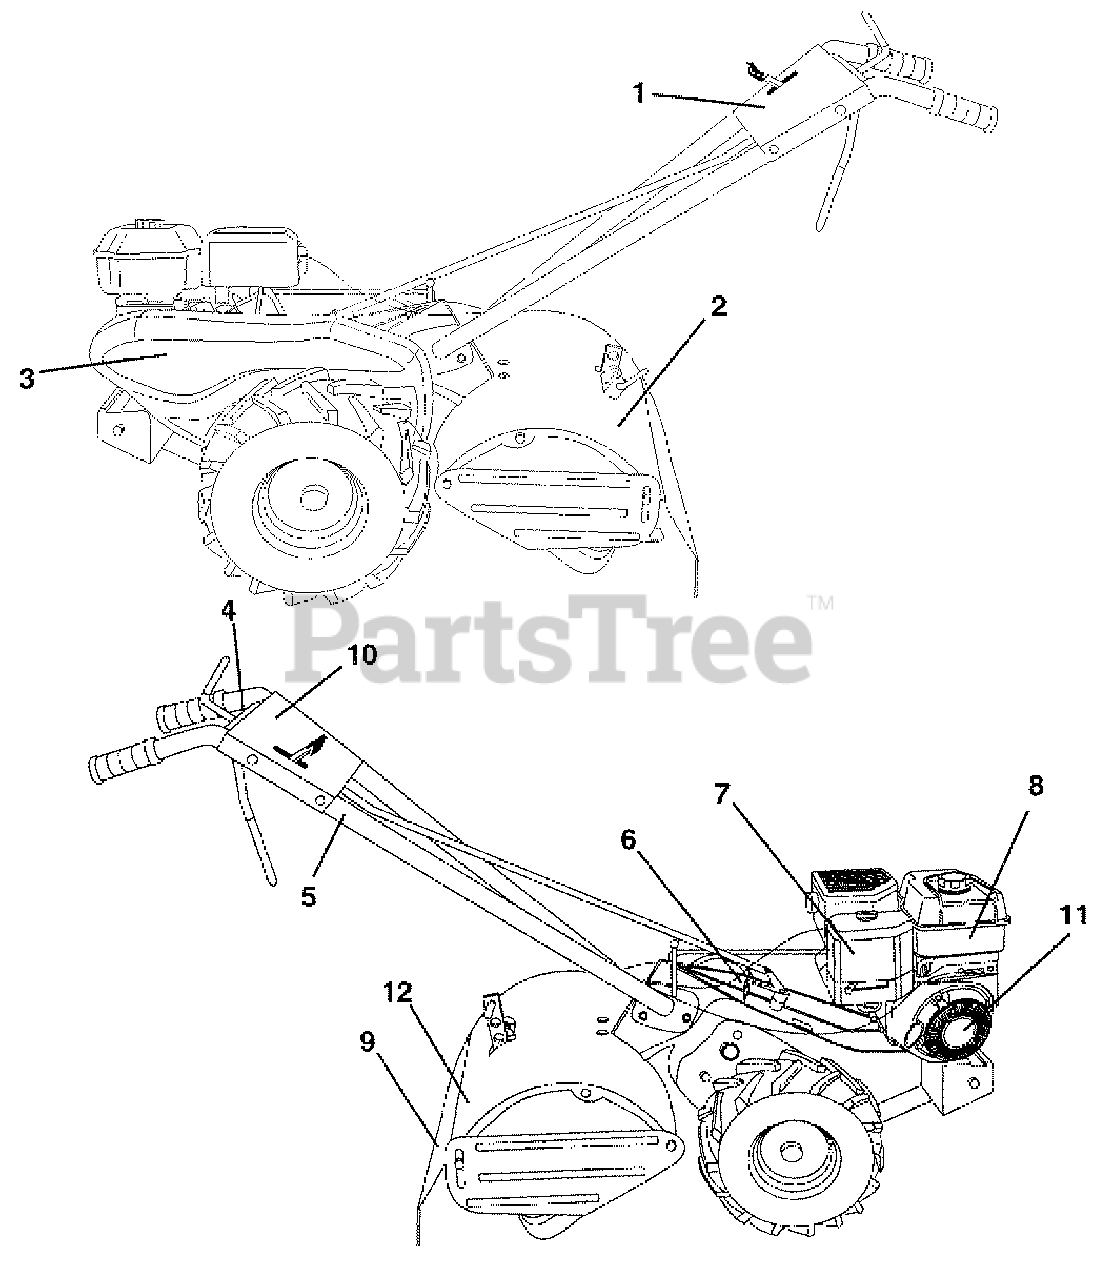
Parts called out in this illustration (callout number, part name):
1	Decal, Logo
2	Decal, Description
3	Decal, Logo
4	Decal, Instruction, Tilling
5	Decal, Hand Placement
6	Decai, Shift Indicator
7	Decal, Briggs & Stratton
8	Decal, OHV N-l/C
9	Decal, Warning, Rotating Tines
10	Deal, Reverse
11	Decal, Rewind INTEK
12	Decal, Tine Shield Wrng Dom
12	Manual, Owner's (English)
12	Manual, Owner's (Spanish)
